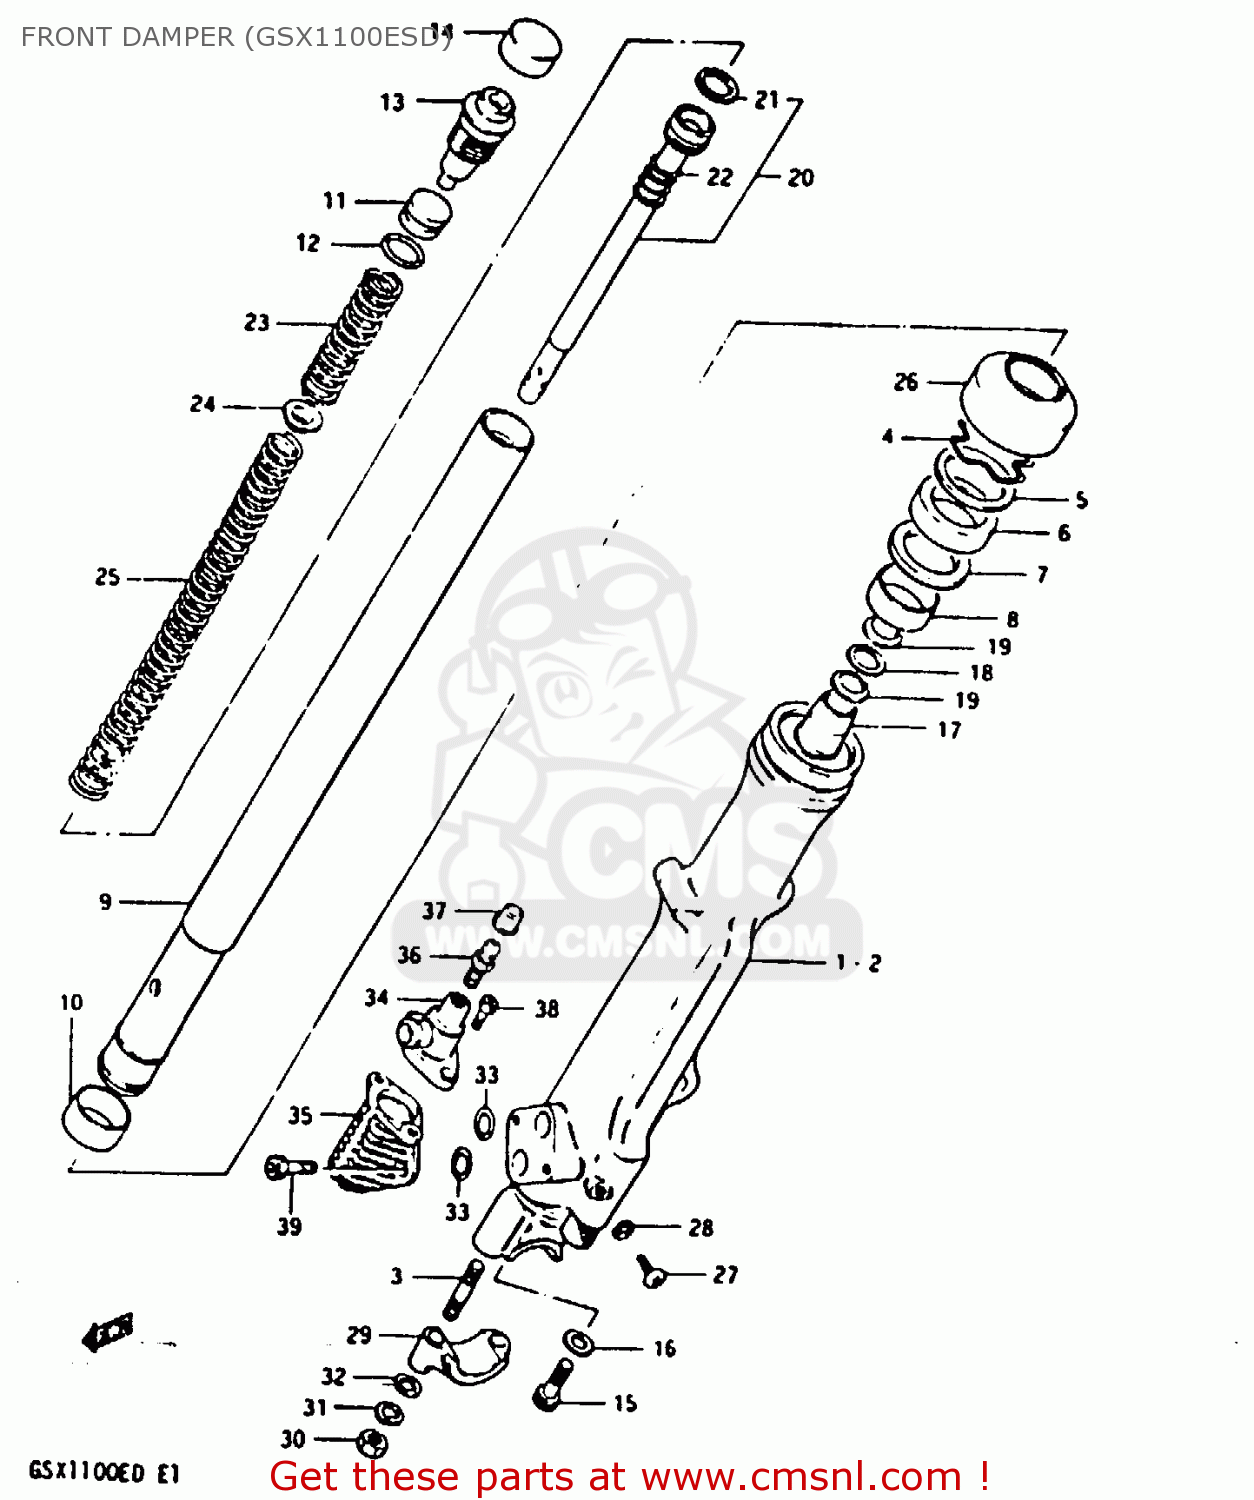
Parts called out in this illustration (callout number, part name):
1	OUTER TUBE, RH
2	OUTER TUBE, LH
3	STUD 8X30
4	RING,STOPPER
5	WASHER. FRONT FORK
6	OIL SEAL,FRONT FORK
7	WASHER
8	METAL,SLIDE
9	INNER TUBE
10	METAL,FRONT FORK PISTON
11	PISTON,FREE
12	O-RING
13	CAP
14	CAP,RUBBER
15	BOLT,FORK CYLINDER(10X25)
16	GASKET (NAS)
17	PIECE,OIL LOCK
18	WASHER
19	SPRING,LEAF
20	CYLINDER
21	RING,PISTON
22	SPRING,FORK REBOUND
23	SPRING
24	GUIDE,FRONT FORK SPRING
25	SPRING
26	SEAL,DUST
27	SCREW
28	GASKET,DRAIN,PLUG (NAS)
29	HOLDER,AXLE
30	NUT
31	LOCK WASHER
32	WASHER
33	O RING
34	PLANGER SET,MODULATOR
35	VALVE SET,MODULATOR
36	BREATHER,AIR
37	CAP,BREADER
38	BOLT, MODULATOR (5X12)
39	BOLT,FRONT FORK
